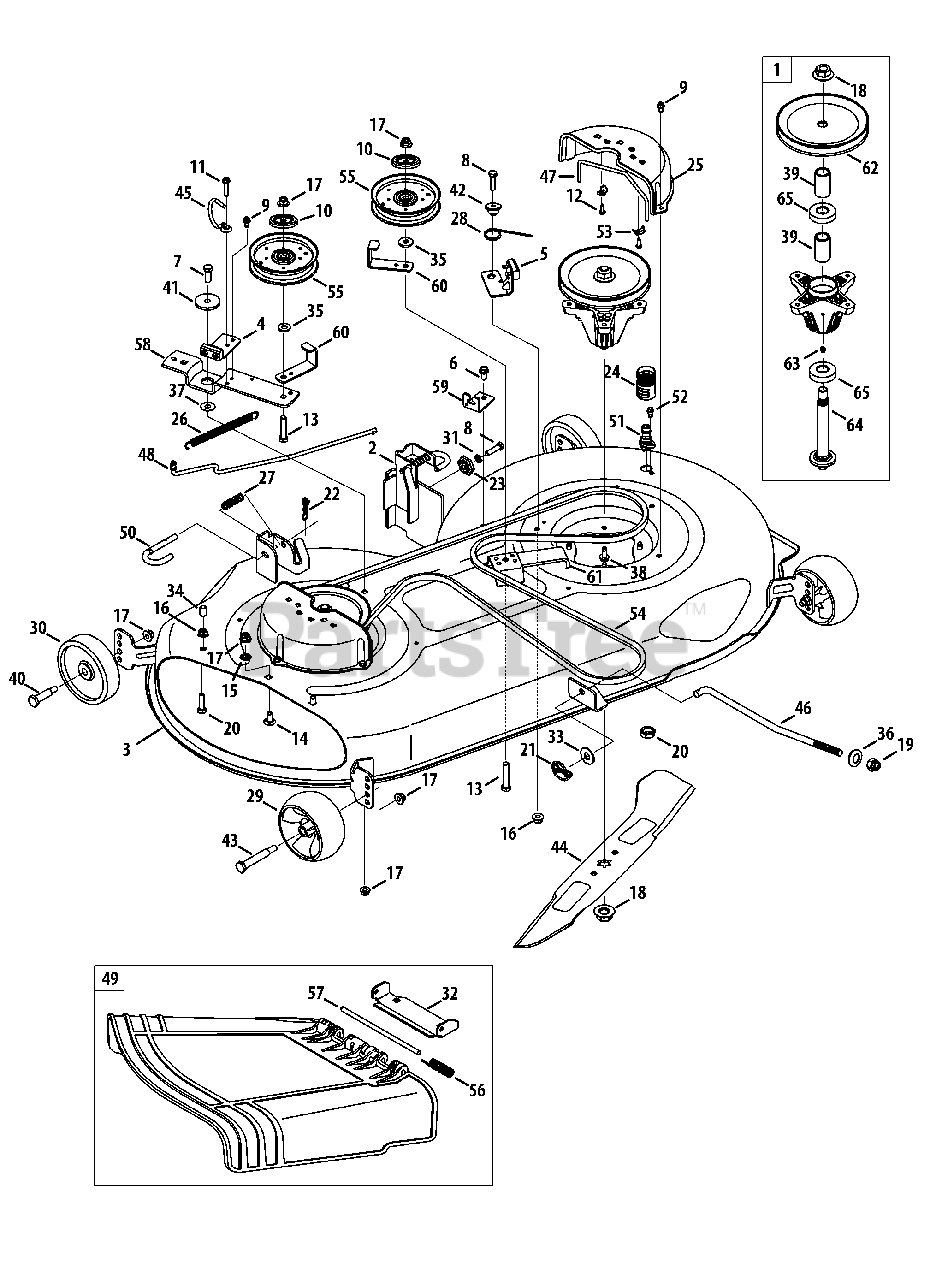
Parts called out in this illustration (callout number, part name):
1	Spindle Assembly, Pul 6.93 Dia
2	Bracket Assembly, Deck Hanger, LH
3	Deck, Offset, 46"
4	Brake Assembly, Deck, 42/46
5	Brake Assembly, Deck, 46"
6	Screw, Self-tapping, 5/16-18, .750,
7	Hex Screw, 3/8-16, 1.00, Gr5, Std
8	Hex Screw, 5/16-18, 1.25, Gr5, Std
9	Screw, Self-tapping, 1/4-20, 0.500
10	Pulley Cap
11	Screw, Self-tapping, 1/4-20, .750
12	Screw, B, #10-16, 0.625
13	Hex Screw, 3/8-16, 2.00, Gr5, Std
14	Bolt, Carriage, 3/8-16, 0.75, Gr1
15	Nut, Push, 3/8
16	Nut, Flange Lock, 5/16-18, Nylon
17	Nut, Flange Lock, 3/8-16, Nylon
18	Nut, Flange, 5/8-18
19	Nut, Lock, 1/2-13
20	Hex Cap Screw, 5/16-18 x 1.00
21	Pin, Lynch, .1875
22	Bow-Tie Cotter Pin, 72
23	Gear, Deck Adjustment
24	Adapter, Water Port
25	Belt Cover, Universal
26	Spring, Extension, .62 x 6.12
27	Spring, Compression, .535 x 1.751
28	Spring, Torsion, .992 I.D x 1.17 O.D
29	Wheel, Deck, 5.0 Dia Ball
30	Wheel, Deck 5.0 x 1.38
31	Washer, Lock, 5/16, Regular Duty
32	Bracket, Chute, 46
33	Washer, Flat, .531 x 1.25 x .100
34	Cap, .290 x .500
35	Washer, Flat, .385 x .870 x .092
36	Washer, Bell, .63 x 1.25 x .18
37	Washer, Flat, .385 x 1.0 x .030
38	Self Tapping Screw, 5/16-18 x .75
39	Spacer, .792 x 1.060 x 1.860 Lg
40	Bolt, Shoulder, .496 x 1.525, 3/8-16
41	Spacer, Shoulder, .8840 x .190
42	Spacer, Shoulder, .50 x .145
43	Bolt, Shoulder, .496 x 2.50, 3/8-16
44	Blade, Cut, 23.25" 2-In-1, Cub
45	Rod, Belt Keepr, 42 Idler
46	Rod, Lift, Deck, Frt, 13.7
47	Rod, Keeper, Belt
48	Rod, Control, Brake 46"
49	Chute Assembly, 46" Offset Cub
50	Rod, Deck Release
51	Deck Wash Nozzle
52	Shoulder Screw, 1/4-20 x 0.50
53	Clamp, Casing
54	Belt, V-Type, A-Sec
55	Pulley, Idler, 4.25"Dia
56	Spring, Torsion, .44 I.D. x 2.0
57	Pin, Hinge, 7.96
58	Bracket, Idler, Pivot, 46
59	Bracket, Cable, Deck Engagement
60	Bracket, Guard, Belt, 4.25 Pulley
61	Bracket, Support, Deck Idler
62	Pulley, Deck, 6.93 Dia
63	Lube Fitting, 3/16
64	Shaft, Spindle, 6.11 Lg.
65	Bearing, Ball, .787 x 1.85 x .551
